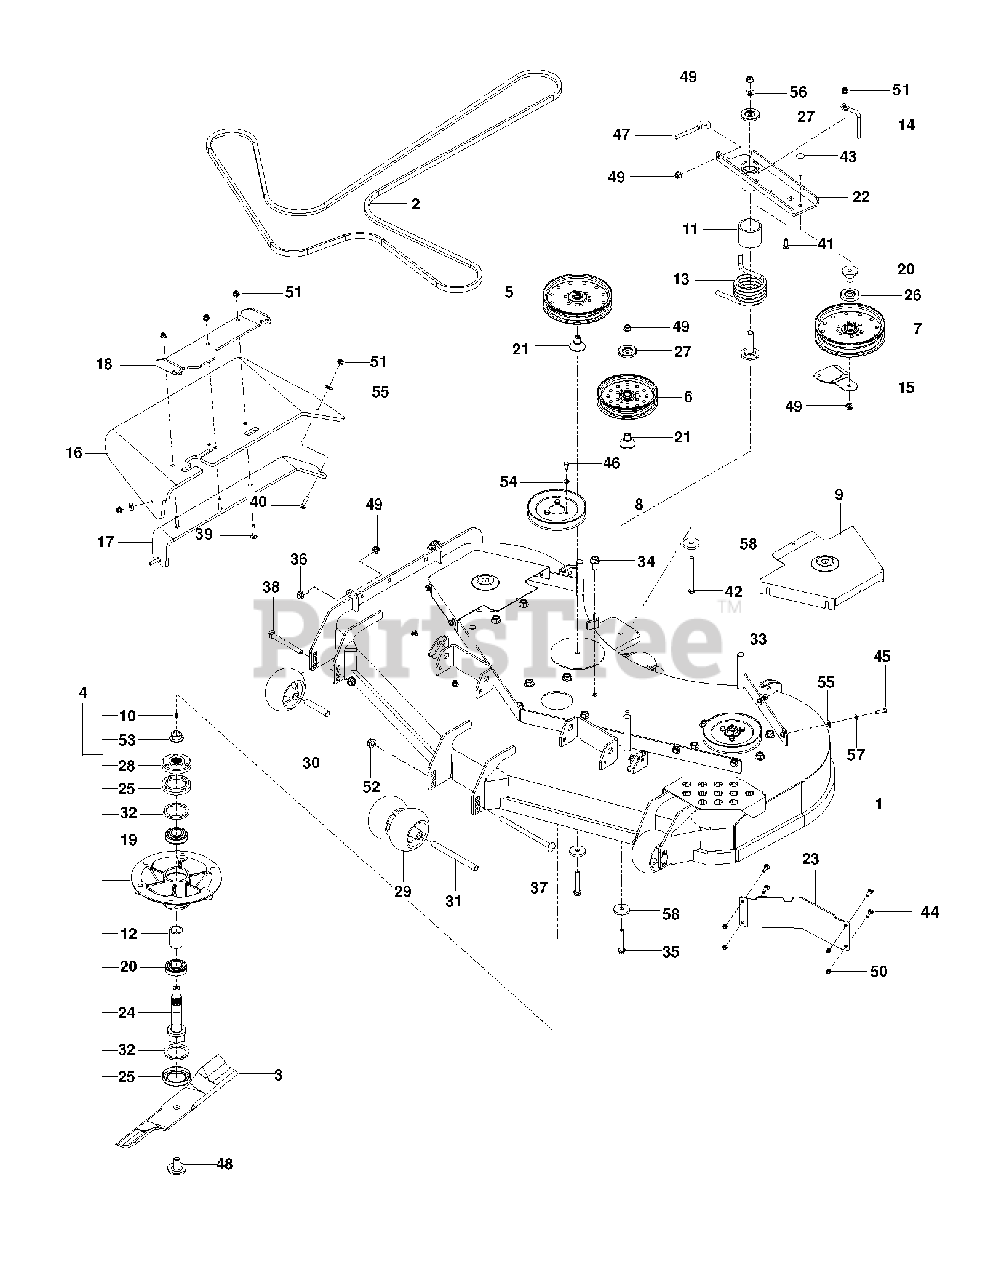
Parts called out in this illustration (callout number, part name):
1	DECK W/SAFETY DECALS 60"
2	BELT, "5V", 176"
4	SPINDLE ASM. 10"
5	PULLEY - 7" NARROW
6	PULLEY IDLER, 6" NARROW
7	PULLEY - IDLER 7"
9	SHIELD, BELT, 60" BLUE
10	ZERK
12	SPACER - BEARING
15	BELT GUIDE, BLK
16	CHUTE, DISCHARGE 48-52
17	BRKT, CHUTE SUPPORT BLACK
18	BRKT - CHUTE MTG BLACK
19	BEARING - 206KRR8
20	BEARING, IDLER ARM
21	BEARING, IDLER PIVOT
23	BAFFLE, DIVERTER 54"/60" LH
24	SHAFT - SPINDLE
25	CUP - DEBRIS
26	SHIELD, DUST
27	DUST SHIELD
28	HUB - PULLEY
29	ROLLER, GAUGE .635 BORN
30	TUBE, ROLLER AXLE
31	TUBE, ROLLER AXLE LONG
32	V-RING, 55MM
33	U-CLIP 5/16-18 NUT RETAINER
35	HHFS 3/8-16 X 2 3/4
36	HHFS 3/8-16 X 1 GRD 5 ZD
37	RHSNB 1/2-13 X 8 GR5 ZD
38	RHSNB 1/2-13 X 4.75 GR5 ZD
39	RHSNB 5/16-18 X 1-1/2 GR 5 ZD
40	BOLT, CARRIAGE 5/16X1-1/4
41	RHSSNB 5/16C X 1.0
42	HCS 3/8-16 X 4-1/2 GR 8 ZD
43	CARRIAGE BOLT 3/8-16 X
45	HCS 5/16C X 1
46	HCS 5/16-18 X 1/2 GR 5 ZD
48	BLADE BOLT/WASHER
49	NUT 3/8-16 HEX FLG NYLOC ZD
50	NUT 1/4-20 NYLOC
51	5/16-18 NYLOC FLANGE NUT
52	NUT, 1/2-13 HEX FLG NYLOC ZD
53	NUT FLANGE 3/4-16
54	WASH 5/16 DISC SPRING ZD
55	WASHER 5/16 FLAT
56	WASHER, 3/8 THICK
57	WASHER 5/16 LOCK
58	SPINDLE WASHER
